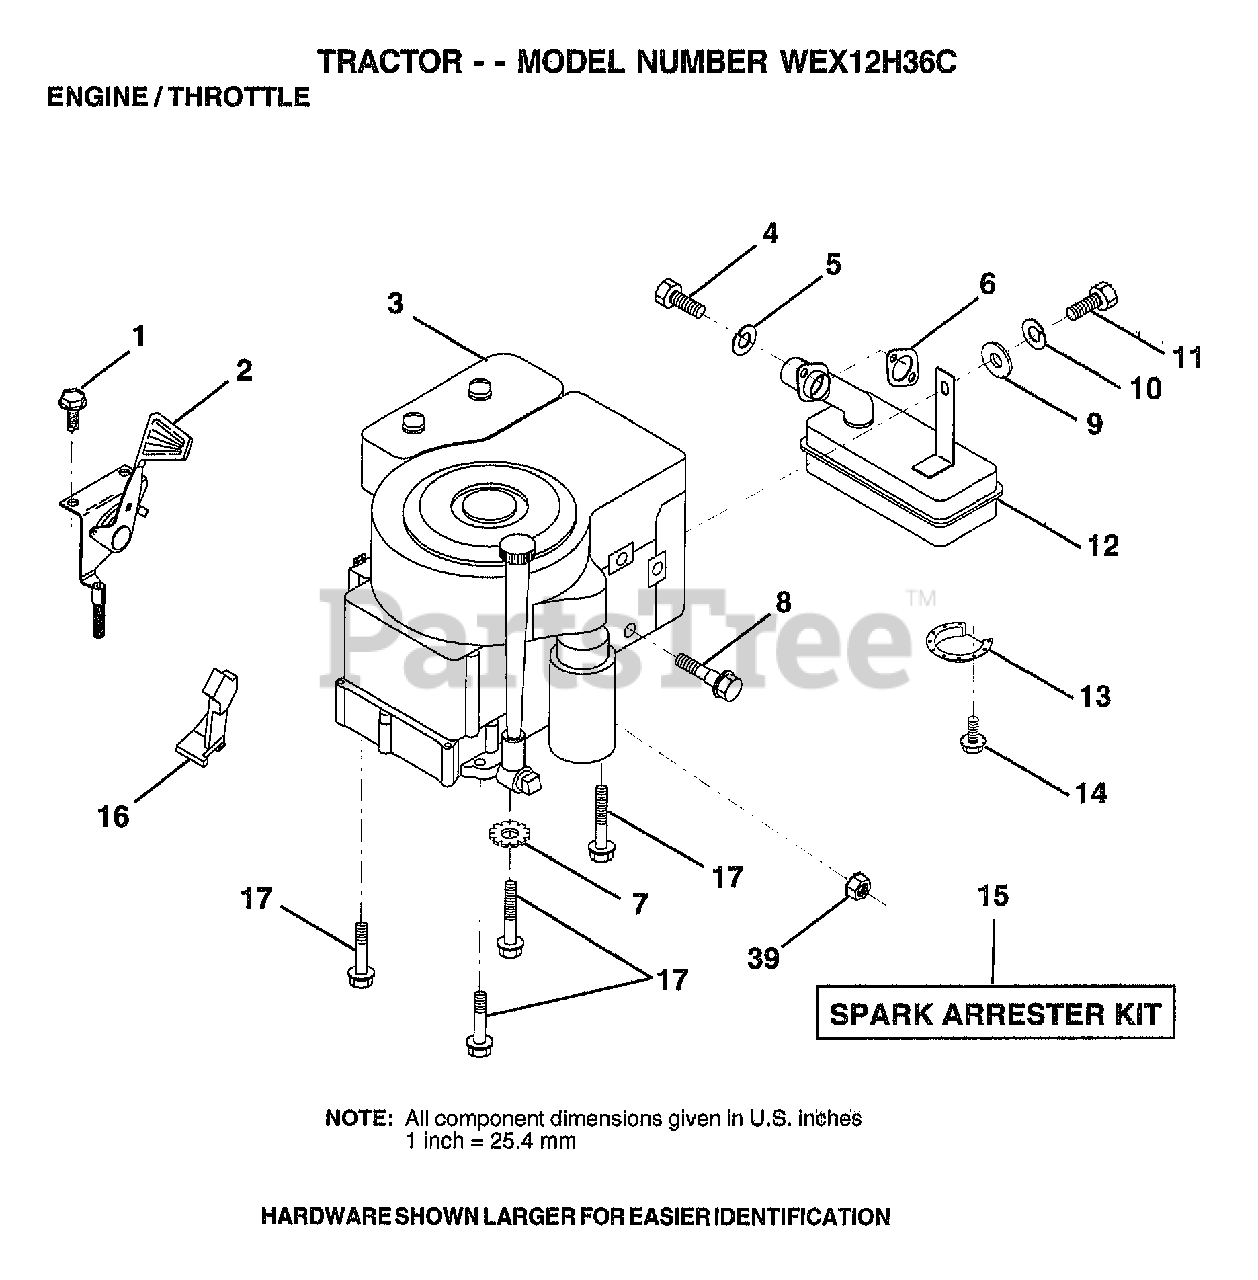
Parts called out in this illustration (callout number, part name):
1	SCREW LT
4	SCREW
5	LOCKWASHER
7	LOCKWASHER
8	BOLT T
10	LOCKWASHER
12	MUFFLER
13	DEFLECTOR.222573
16	"STOP,DASH THROTT"
17	SCREW LT
39	NUT
